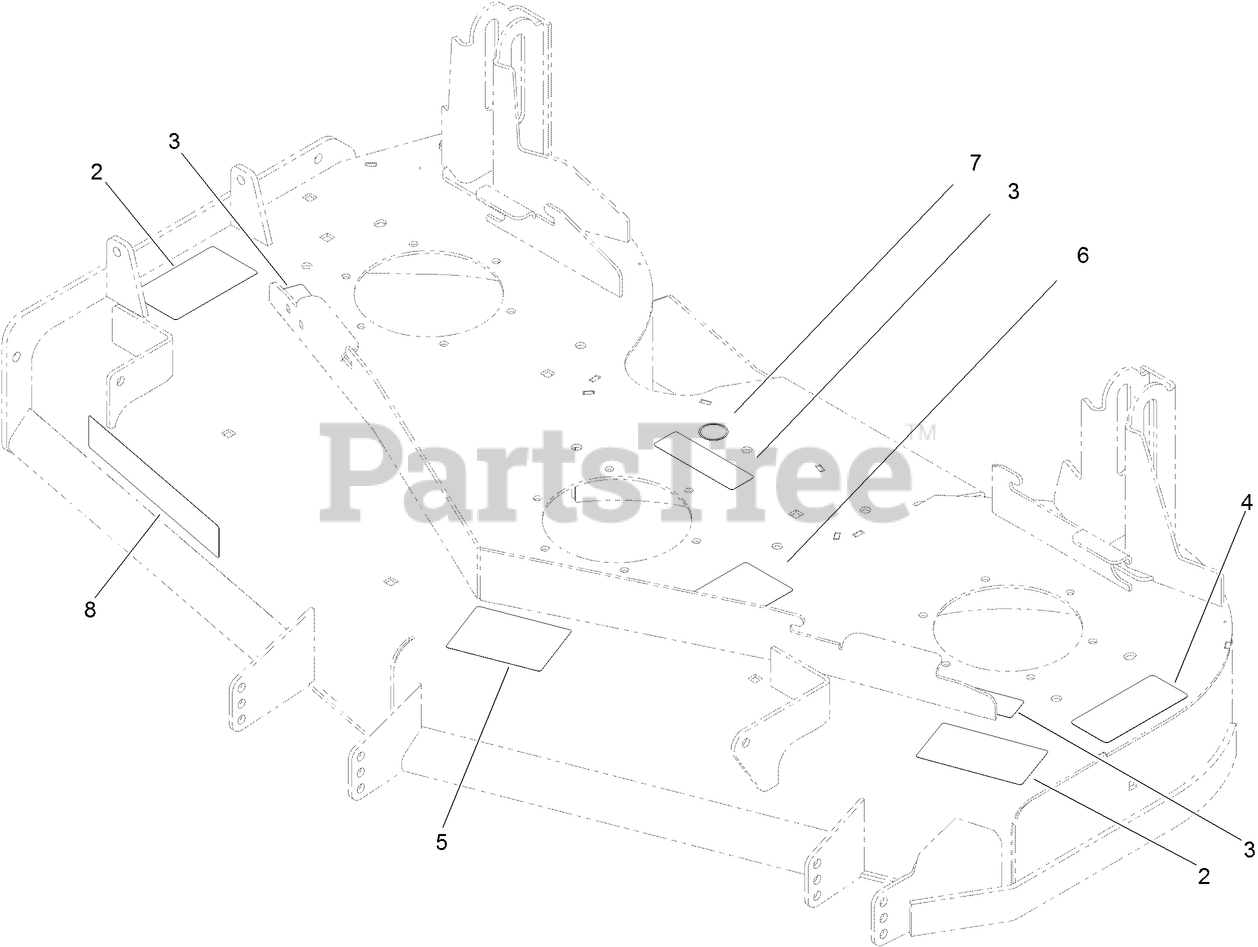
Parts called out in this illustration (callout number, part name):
2	DECAL-DANGER
3	DECAL-COVER, MISSING
4	DECAL-TORQUE, BLADE BOLT
5	DECAL-SCALP, ANTI
6	DECAL-ROUTING, DECK BELT
7	DECAL-GREASE
